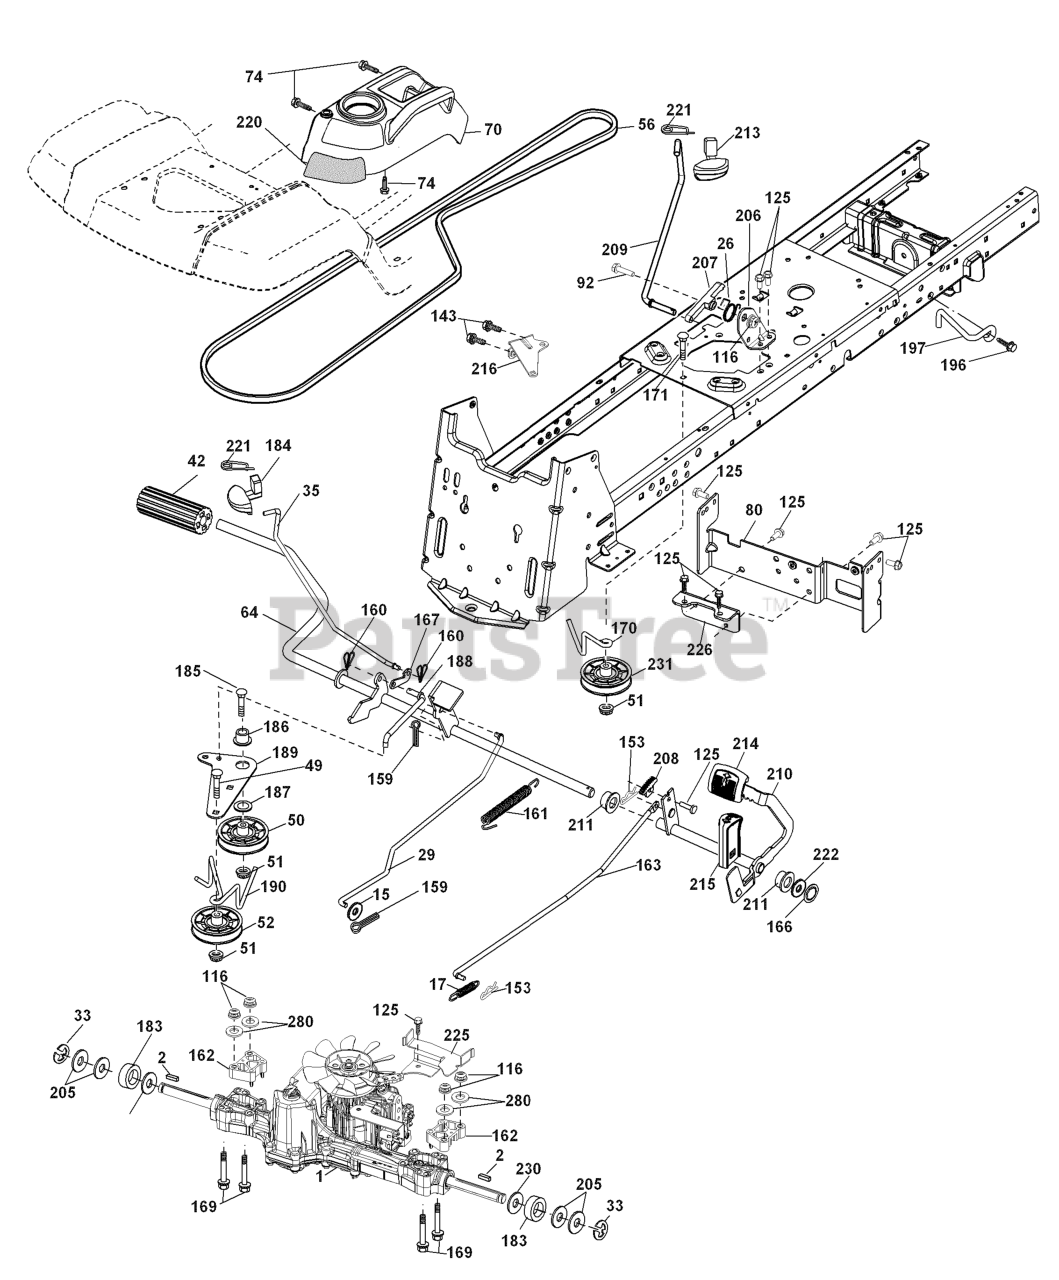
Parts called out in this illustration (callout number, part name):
1	TRANSAXLE.K46BN.PEDAL CONTROL
2	SQUARE KEY
7	HUB.ASM.WHEEL.REAR.22"
9	HUB BOLT
15	WASHER
17	SPRING.BRAKE.K46
26	SPRING.RETURN.CRUISE
29	ROD.BRAKE.K46
35	ROD.BRAKE.PARKING.GT.H
42	PEDAL COVER T
50	IDLER.FLAT.910.OFFSET
51	NUT LOCK FLG 3/8-16 UNC
52	IDLER.V-GROOVE.910.OFFSET
56	V-BELT.MOWER.92.40.42/K46
64	SHAFT.ASM.PEDAL.BRK.CNTR
70	RP CONSOLE.ASM.PCH.W/TB
74	SCREW.HI-LO.CONSOLE
80	STRAP TORQUE
92	BOLT
116	NUT LOCK HEX FLANGE 5/16-18
125	SCREW
143	Screw Thdrol 5/16-18 x 1/2
153	RETAINER M
159	COTTER PIN
160	RETAINER CLIP
161	SPRING.RETURN.CLUTCH.2006
162	SPACER TRANS
163	ROD.CONTROL.PEDAL.K46
166	NUT.PUSH.625.2006
167	LATCH.BRAKE.SPRING
169	BOLT YT
170	KEEPER.V-IDLER.CENTER.
183	SPACER AXLE
184	HANDLE.PARKG.BRK.HUSQ X667
185	BOLT
186	SPACER.RETAINER
187	WASHER 12/32X2X10GA
188	RP.LINK.CLUTCH.GROUND.DRIVE
189	BELLCRANK.GROUND.DRIVE.TEX.
190	KEEPER.BELLCRANK.DRIVE
196	SCREW 3/8-16X1
197	BRKT.ANIT-ROTATION.CLUTCH
206	BRKT.MOUNT.LATCH.CRUIS
207	LATCH.CONTROL.CRUISE
208	GEAR.SECTOR.CONTROL.CR
209	ROD.CONTROL.CRUISE.GT.
210	ROCKER.ASM.PEDAL.CONTR
211	BEARING.NYLON
213	KNOB.CONTROL.CRUSIE.HU
214	PEDAL.FORWARD.TEX.GT.4
215	PEDAL.REVERSE.TEX.GT.4
216	BRACKET.PULLEY.IDLER.W/TEX
220	REFLECTOR.RH.TEX GT
221	RETAINER.SPRING.CLIP.H
222	WASHER
225	KEEPER.BELT.TRANSAXLE.K46
226	BRACKET.MOUNT.TORQUE.K46.TLT
230	WASHER.HARDENED
231	IDLER.V-GROOVE.1.688.OFFSET
280	WASHER T
